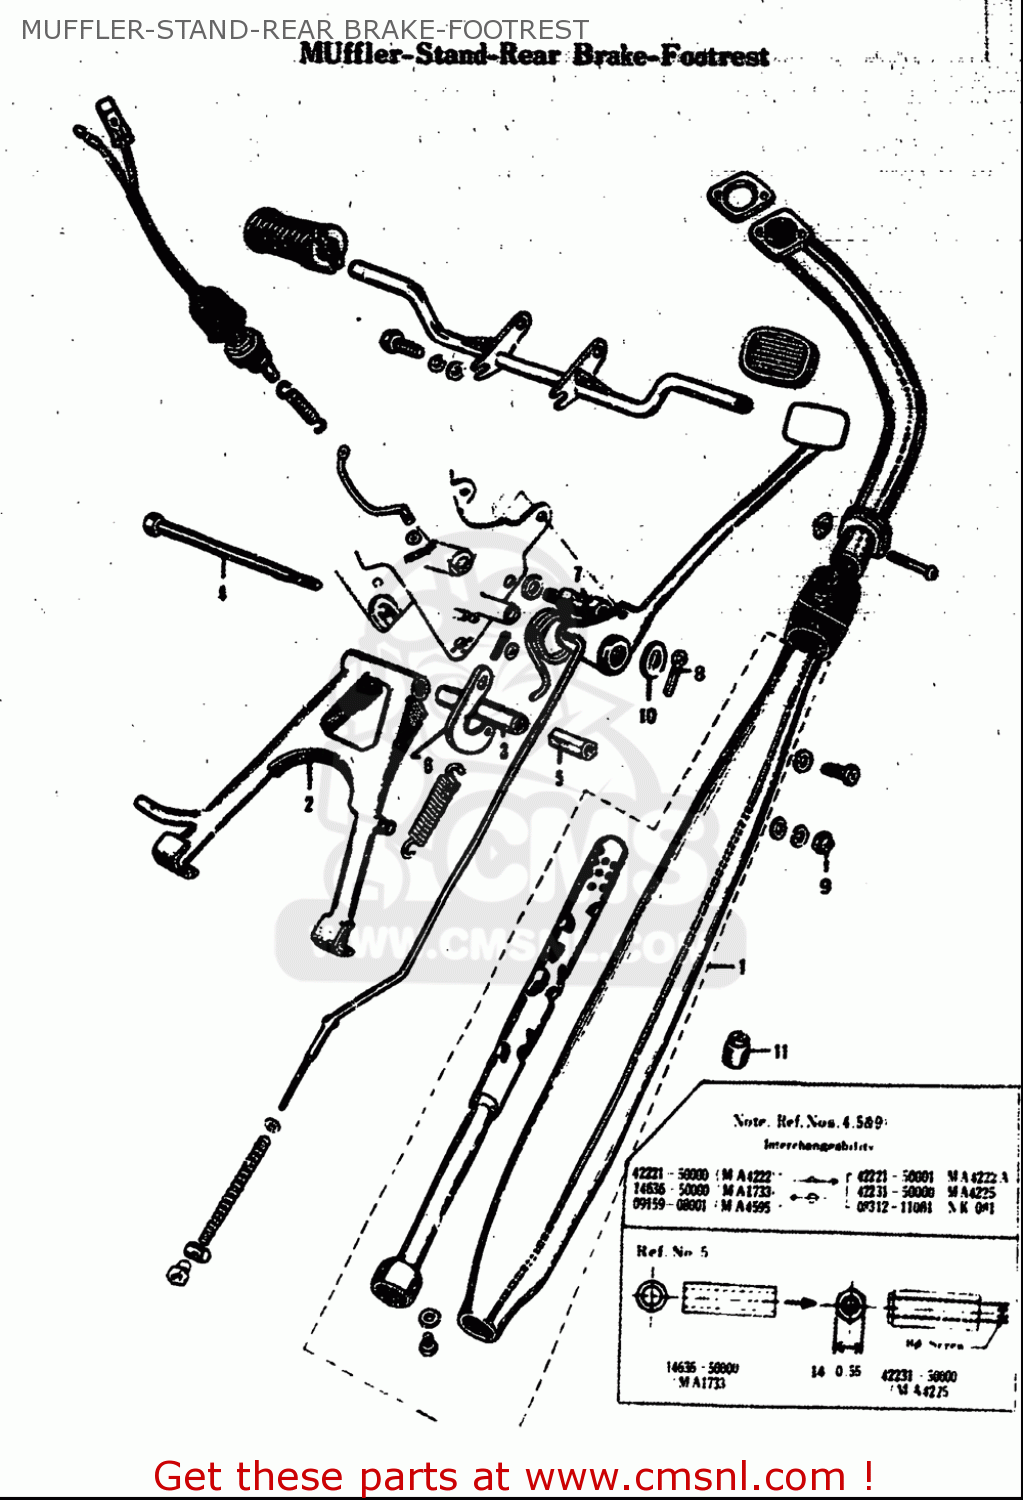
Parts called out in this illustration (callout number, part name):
9	NUT
10	WASHER(15.5X26X2.3)
11	CUSHION
